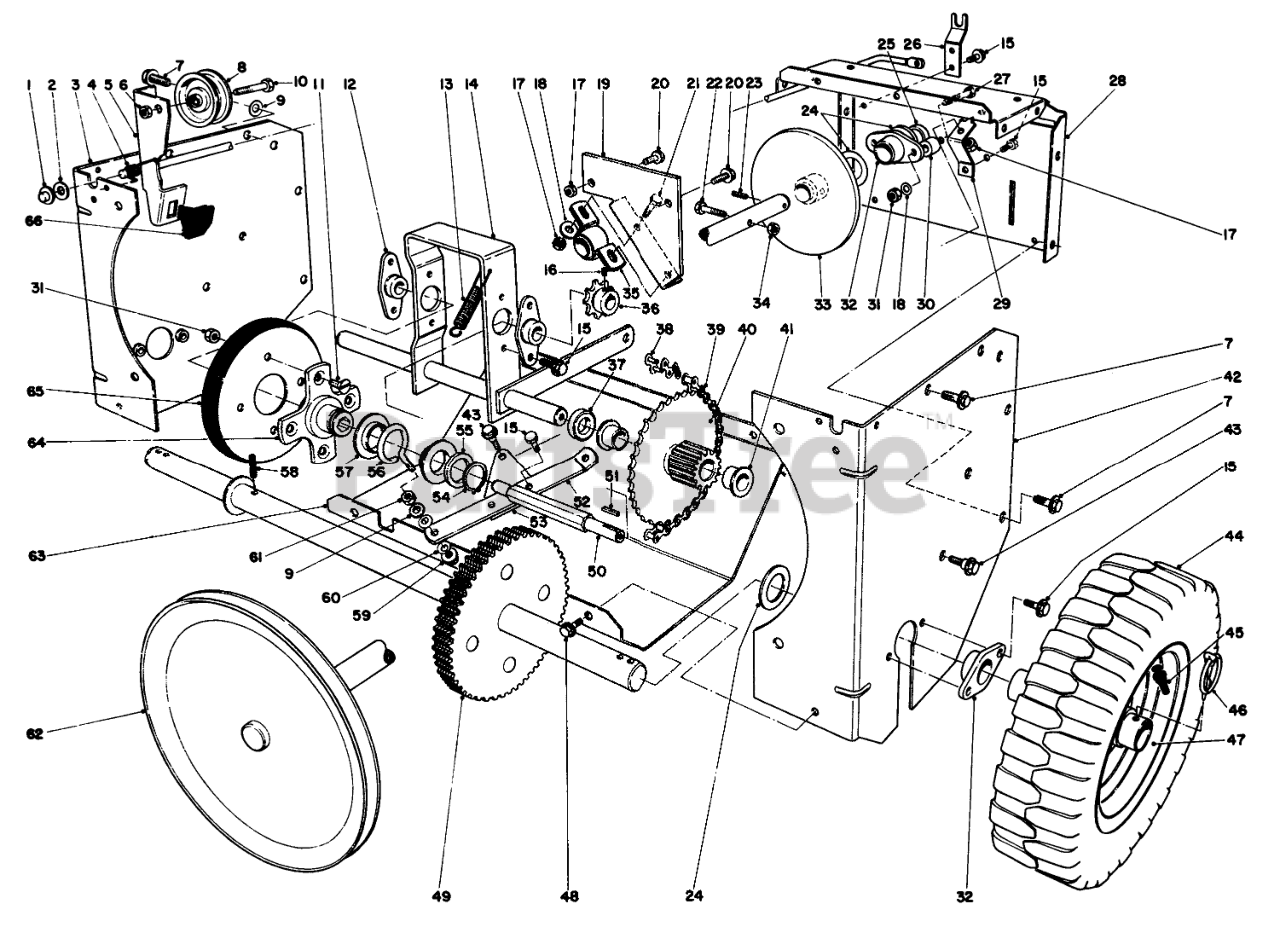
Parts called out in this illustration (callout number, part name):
1	PUSH NUT
2	WASHER-FLAT
3	RH TRACT SIDE PLT R
4	TORSION CLUTCH SPRING
5	Clutch Rod (Incl. Ref. #66)
6	NUT-HEX
7	SCREW-HHFTF
8	PULLEY-IDLER
9	WASHER-FLAT
10	SCREW-HH
11	5/16-18X5/8 FLT HD MS
12	BEARING-WHEEL, FRICTION
13	TENSION SPRING
14	PIVOT SHAFT WA B
15	SCREW-HWHTF
16	SCREW-HSH
17	NUT-LOCK, NI
18	WASHER-PLAIN
19	SHAFT SUPT BRKT B
20	SCREW-HH
21	SCREW-HH
22	SCREW-HH
23	PIN-ROLL, SLOTTED
24	WASHER
25	DRIVE SHAFT SPACER
26	CLUTCH ROD SUPPORT
27	SCREW-HH
28	CENTER FRAME R
29	PIVOT BRACKET
30	BRG STANDOFF
31	Nut
32	AXLE BEARING
33	FRICTION PLT WA
34	NUT-LOCK, CONE
35	PILLOW BLOCK BRG
36	SPROCKET
37	COSHAFT SPACER
38	LINK-CONNECTING
39	ROLLER-CHAIN
40	Gear & Bushing (Incl. Ref. #41)
41	BUSHING
42	LH TRACT SIDE PLT R
43	SHOULDER SCREW
44	Tire
45	STEM-VALVE
46	PIN-LYNCH
47	Wheel
48	SCREW-HWH
49	AXLE & GEAR WA
50	FRICTION WHL SHAFT
52	SHIFT LINKAGE
53	PIVOT PLATE
54	RING-RETAINING
55	WASHER-THRUST
56	SLIDER RING COLLAR
57	SLIDER RING
58	PIN-ROLL, SLOTTED
59	NUT-LOCK, FLANGE
60	WASHER-SPRING
61	Nut
62	PULLEY/SHFT WA
63	LOWER SHIELD R
64	TRACTION DISC HUB
65	FRICTION WHEEL
66	Brake Pad
